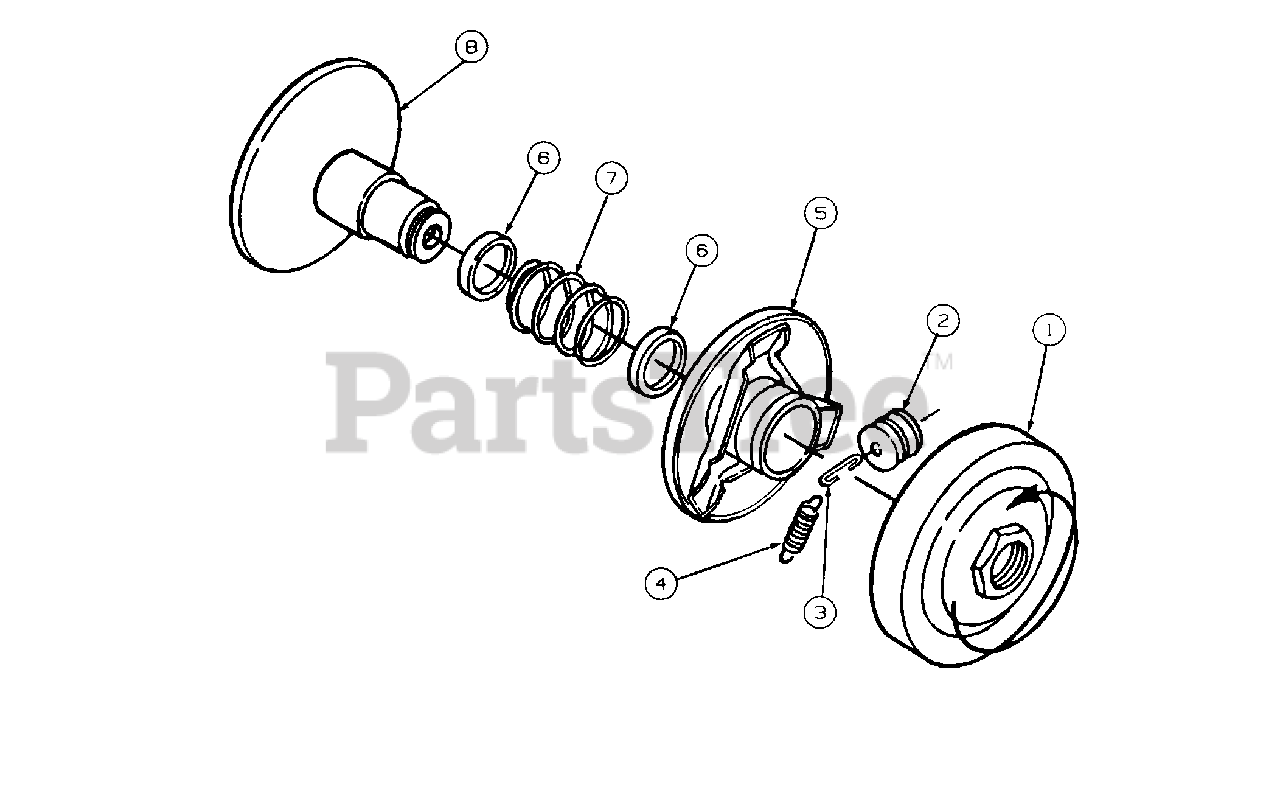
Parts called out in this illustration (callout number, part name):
4	Spring, Yellow
5	Sheave, Movable
7	Spring, Compression
8	Sheave, Fixed
